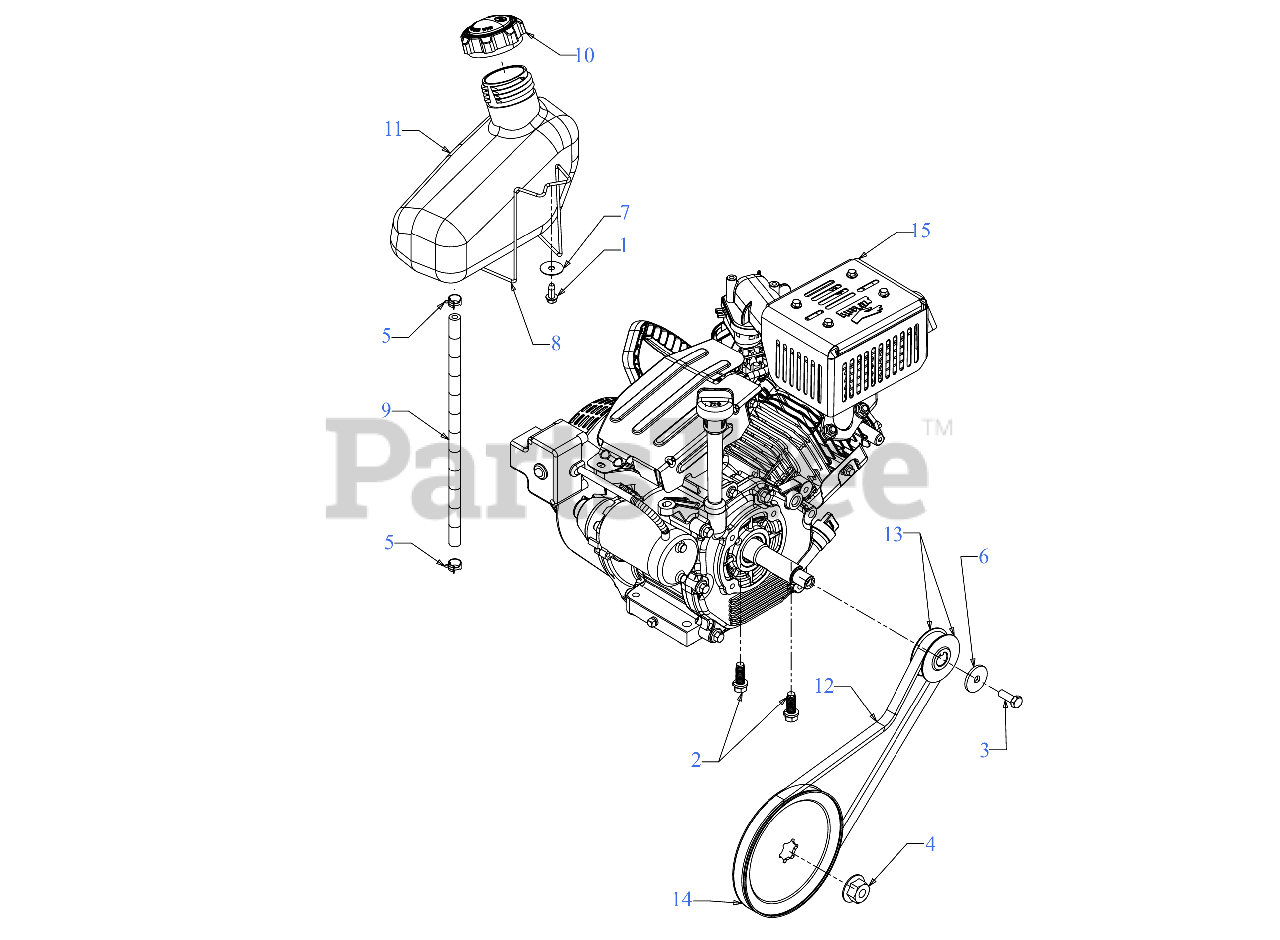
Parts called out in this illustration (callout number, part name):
1	SCREW 1/4-10:.625
2	SCREW 3/8-16 x 1
3	SCREW 5/16-24 x .875 GR5
4	FLANGE NUT W/HUB
5	HOSE CLAMP 1/20
6	WASHER-5/16 x 1.25X 1.27
7	FLAT WASHER
8	SUPPORT WIRE
9	FUEL HOSE LOW PERMEATION 13"
10	FUEL CAP
11	FUEL TANK (2 QT)
12	V-BELT .500 x 35.00LG
13	HALF PULLEY
14	AUGER PULLEY
15	COMPLETE ENGINE 208cc
